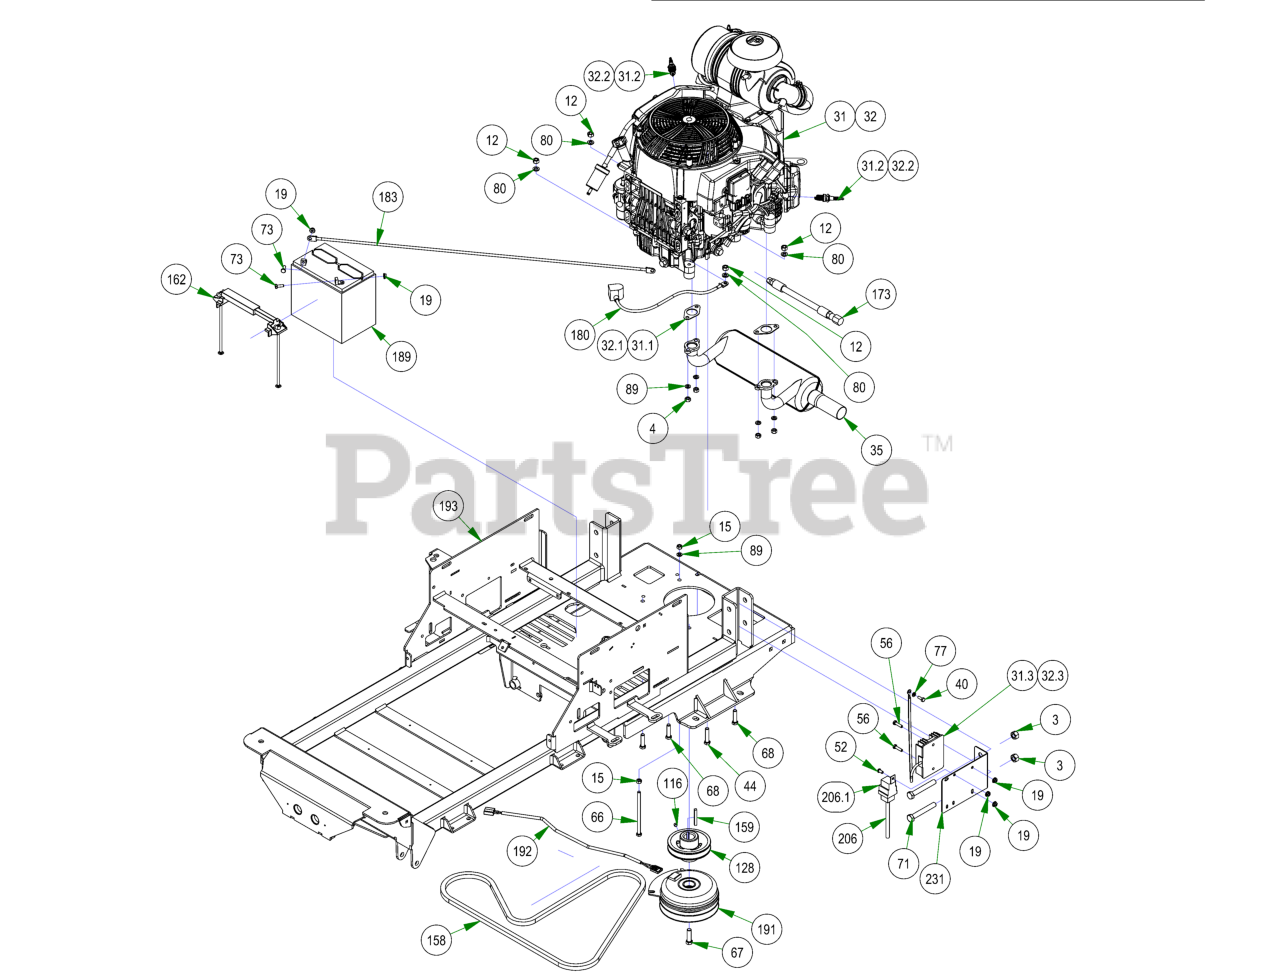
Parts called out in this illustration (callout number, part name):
3	1/2-13 HEX 2-WAY REVERSIBLE CENTER LOCKNUT Grade B ZINC
4	M8-1.25 DIN 934 HEX NUT (CL.8) ZINC
12	3/8-16 HEX NUT ZINC
15	5/16-18 HEX NUT ZINC
19	1/4-20 HEX SERRATED FLANGE NUT HARD/ZINC
31	Honda GXV700 1 1/8"dia x 3.8"Length Crank Shaft
31.1	Exhaust Gasket
31.2	Spark Plug
31.3	Regulator Rectifier for Honda Engine
32	Honda GXV800 1 1/8"dia x 3.8"Length Crank Shaft
32.1	Exhaust Gasket
32.2	Spark Plug
32.3	Regulator Rectifier for Honda Engine
35	2019 Honda Maverick Muffler
40	M6-1.0 X 16MM DIN 933 HEX TAP BOLT (CL 8.8) ZINC
44	3/8-16 X 1-3/4 HEX C/S (GR.5) ZC
52	1/4-20 X 1/2 BUTTON SOCKET CAP SCREW 18-8 STAINLESS STEEL
56	1/4-20 X 1 HEX CAP SCREW (GR.5) ZINC
66	5/16-18 X 5-1/2 HEX CAP SCREW (GR.5) ZINC
67	7/16-20 X 1-1/2 HEX CAP SCREW (GR.8) w/ Patch
68	3/8-16 X 1-1/2 HEX CAP SCREW (GR.5) ZINC
71	1/2-13 X 3-1/2 HEX CAP SCREW (GR.5) ZINC
73	1/4-20 X 3/4 HEX CAP SCREW (GR.5) ZINC
77	1/4 SPLIT LOCKWASHER ZINC
80	3/8 SPLIT LOCKWASHER ZINC
89	5/16 SPLIT LOCKWASHER ZINC
116	5/16-24 X 1/4 SOCKET SET SCREW (CUP PT) PLAIN
128	4 3/4 Motor Pulley
158	75.8" Pump Belt
159	1/4 X 2 SQ MACHINERY KEY 1018 STL PLAIN
162	Hold Down Assembly
173	2019 Honda Oil Drain
180	24 inch Black Cable – MZ/ZT
183	36" Red Battery Cable
189	SP-35 Battery
191	Clutch Assembly
192	Clutch Pigtail
193	2022 Maverick Frame - Painted
206	Honda Maverick HD Pigtail
206.1	2022 Relay for the 086-9019-00
231	Honda Rectifier Mount
